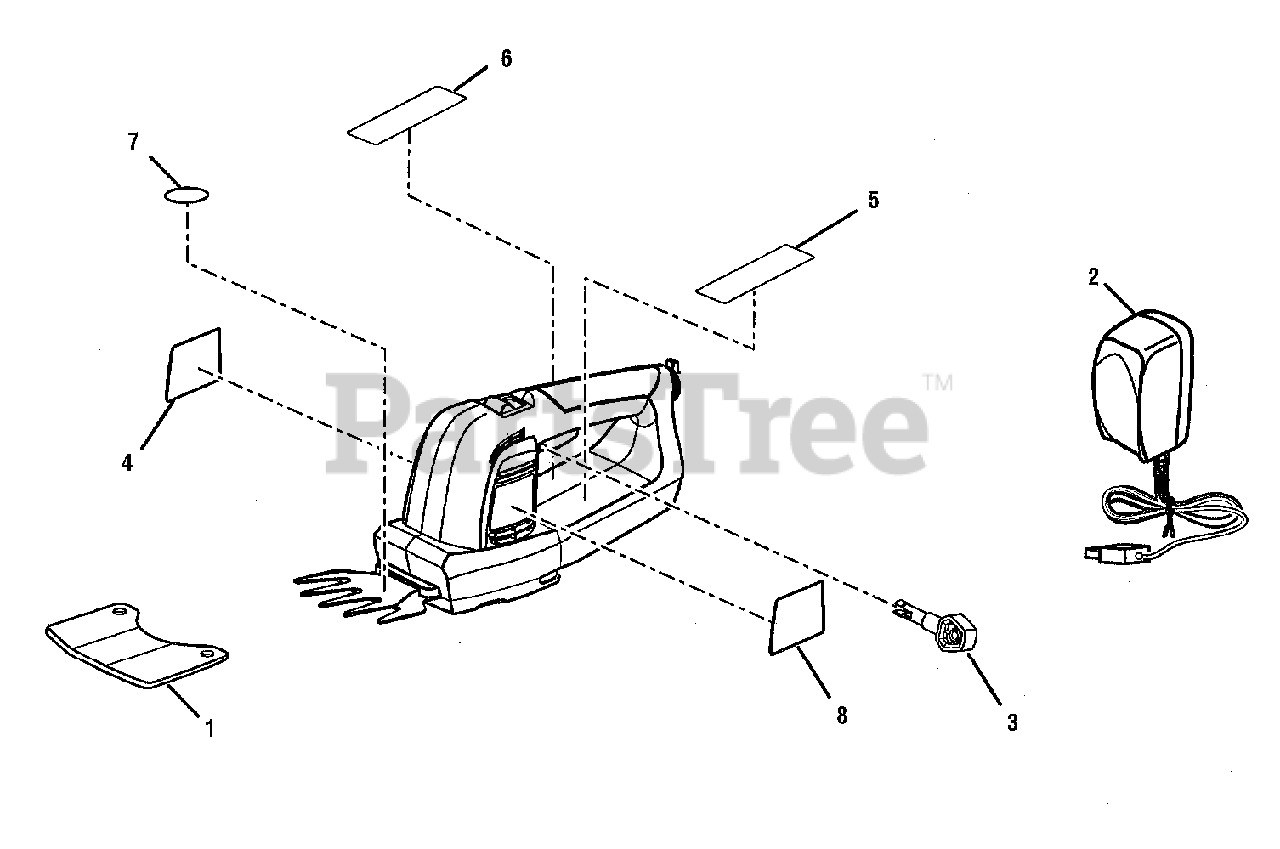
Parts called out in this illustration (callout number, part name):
3	Lock-out Pin
5	Warning Label (English)
6	Warning Label (French/Spanish)
7	No Hands Label
